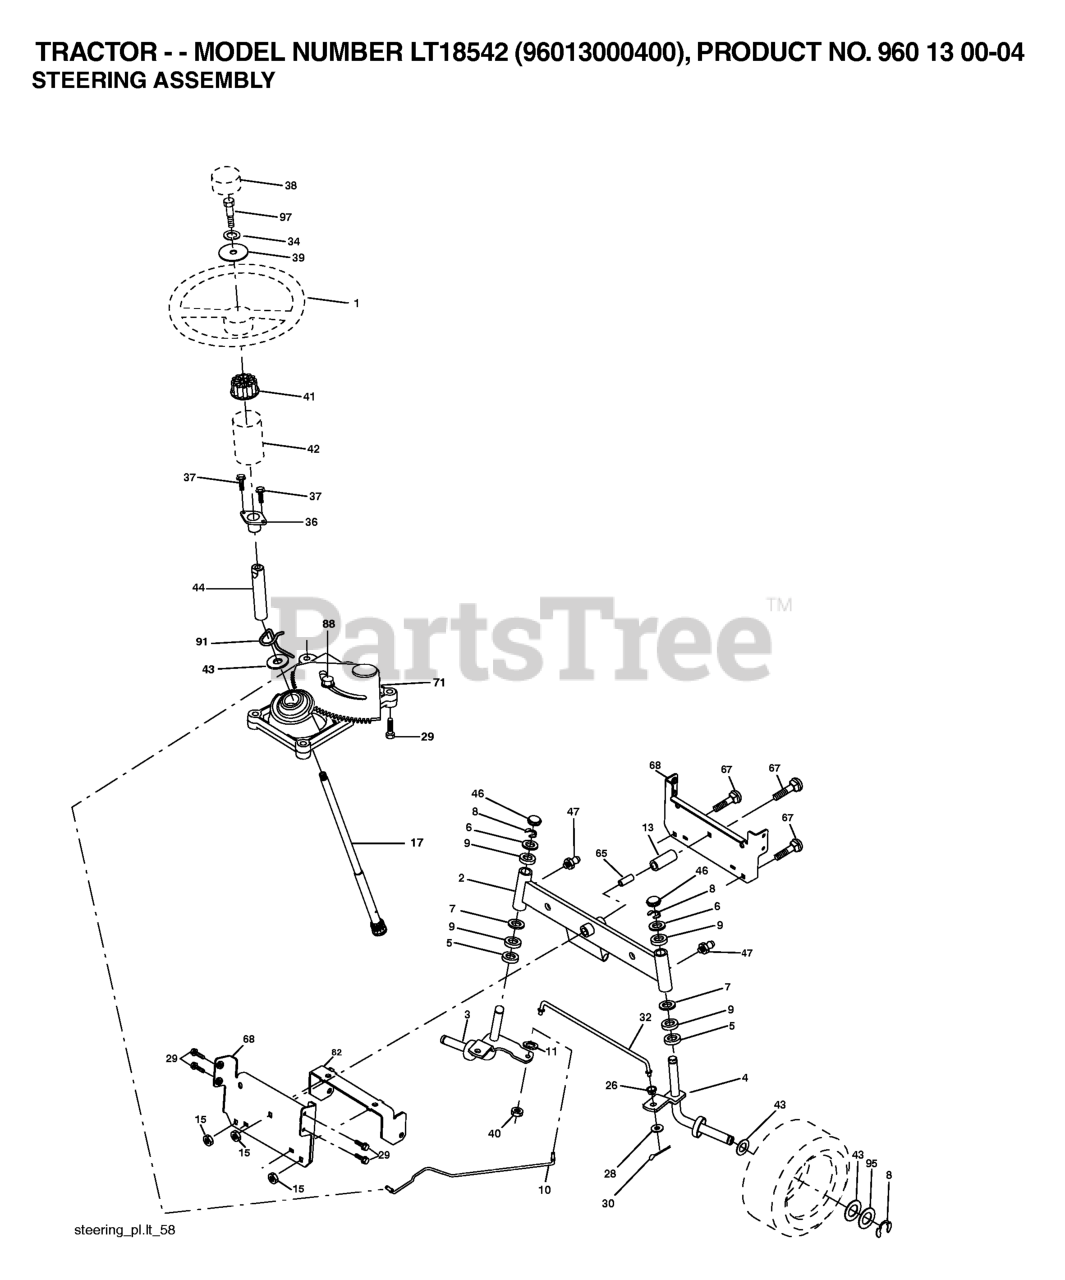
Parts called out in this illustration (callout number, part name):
1	WHEEL.STEERING.LEGEND2.GRY
2	AXLE ASM.
3	SPINDLE.ASM.LH.15"TIRES
4	SPINDLE.ASM.RH.15"TIRES
5	THRUST WASHER
9	BRNG T
10	DRAGLINK.15".TIRES.2001
11	WASHER, LOCK 3/8
13	TUBE, PIVOT AXLE
15	NUT
17	SHAFT STEERING SPLINE
26	BUSHING.DRAGLINK (2 2)
28	WASHER
29	SCREW, 3/8-16X3/4
30	COTTER PIN
32	ROD.TIE.WIRE.FORM
34	WASHER.LOCK.HVY.HLCL.SPR.5/16
36	BUSHING, STEERING
37	SCREW.TT.#10-32X.5.3/8.FLANGE
38	INSERT.CAP.STRG.WH.GRAY
39	WASHER.11/32
40	NUT CROWNLOCK 3/8-24
41	ADAPTER, WHEEL STNG..
42	BOOT STEERING
44	SHAFT.EXTEN.STRG.SPLINE
46	CAP.SPINDLE.BLACK
47	FITTING.GREASE.TAPERED
65	SPACER BRACE AXLE
67	BOLT CARRIAGE
68	BRACE.AXLE.15"TIRES
71	STEERING ASM
82	BRACKET
88	BOLT, SHOULDER 7/16-20
91	CLIP.STEERING
95	WASHER.HARDENED
